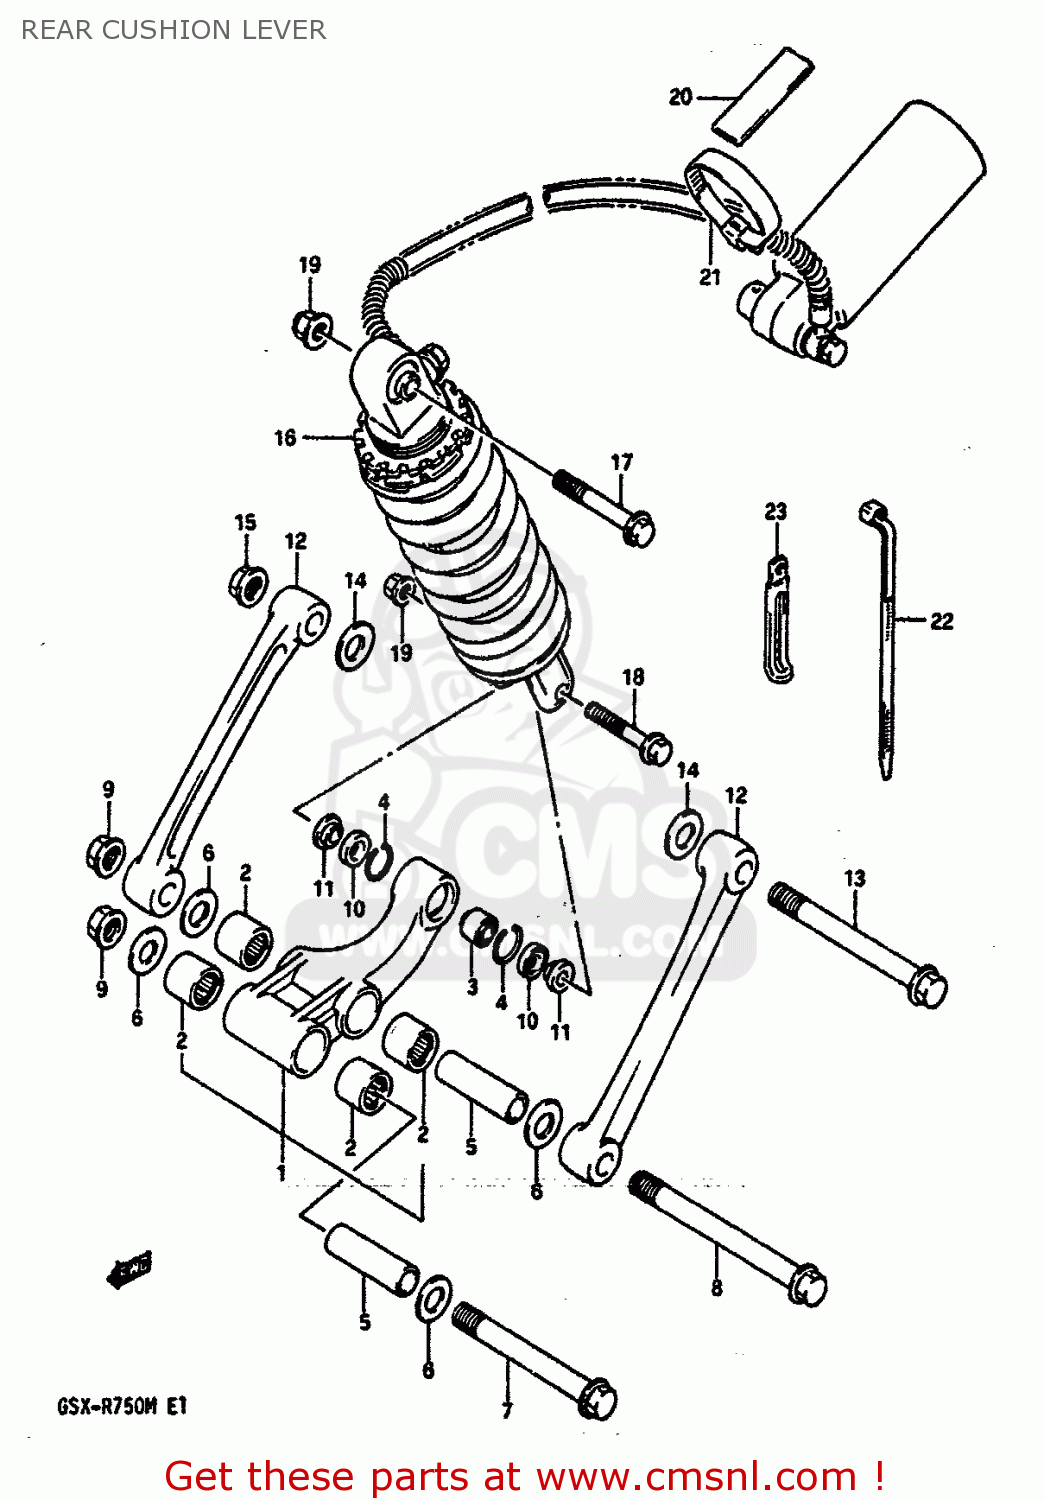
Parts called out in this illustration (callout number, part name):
1	LEVER SET,REAR CUSHION
2	BEARING(20X27X23.5)
3	BEARING,RR CUSHION LEVER
4	RING,STOPPER
5	SPACER,RR CUSHION LEVER
6	WASHER
7	SHAFT,RR CUSHION LEVER FR
8	SHAFT,RR CUSHION ROD
9	NUT
10	DUST SEAL,RR CUSHION LEVER RR
11	SPACER
12	ROD,REAR CUSHION
13	SHAFT,RR CUSHION ROD
14	WASHER
15	NUT
16	ABSORBER ASSEMBLY,REAR SHOCK
17	BOLT
18	BOLT(10X54)
19	NUT
20	CUSHION,RESERVOIR TANK
21	CLAMP
22	CLAMP(L:165)
23	CLAMP
